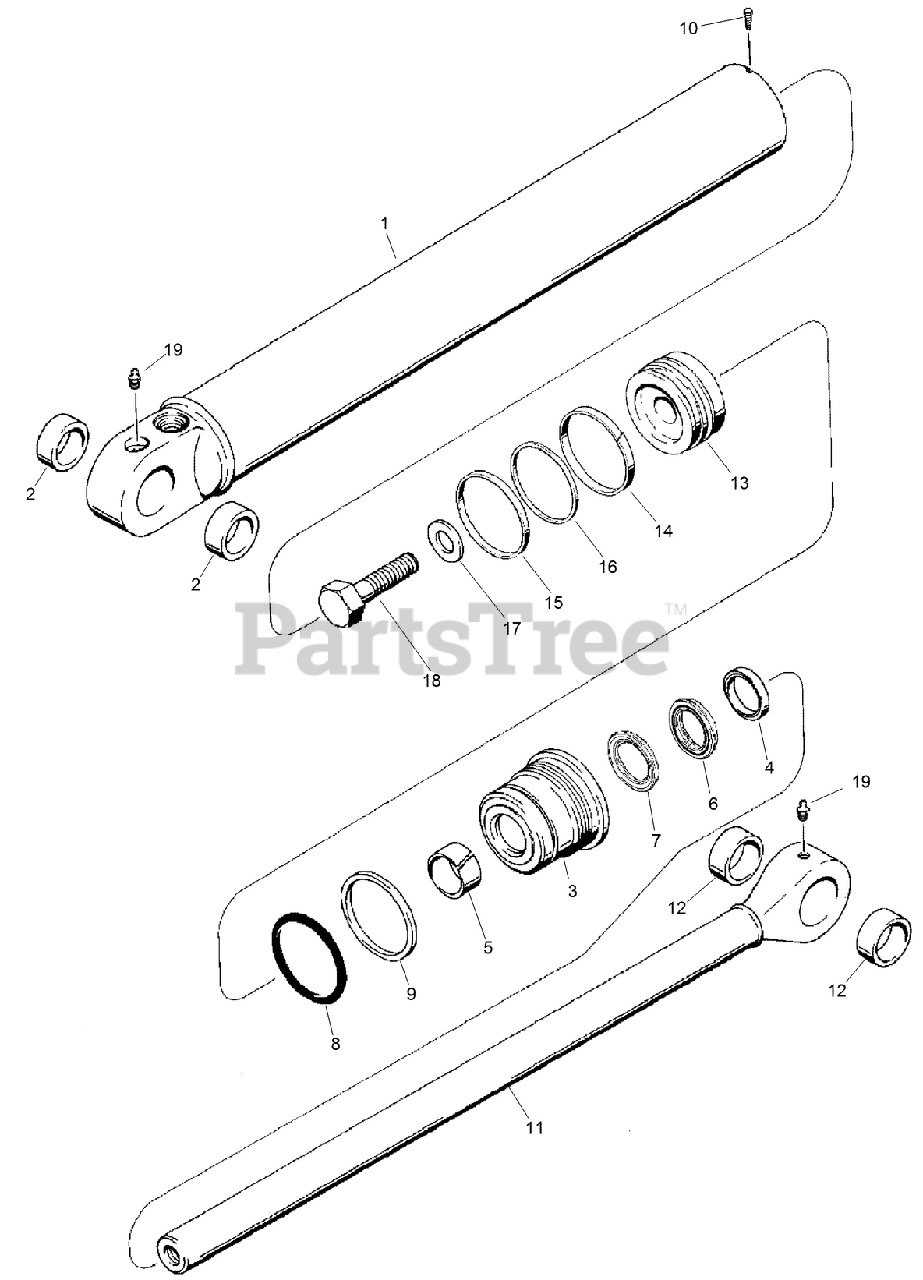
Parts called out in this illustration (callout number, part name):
1	TUBE-Cylinder
2	BUSHING
4	WIPER-ROD
5	BEARING-ROD
6	SEAL-Rod, NSS, order 1543256C1 kit, see below
7	SEAL-Buffer, NSS, order 1543256C1 kit, see below
8	O-RING
9	RING-BACKUP
11	ROD-Piston, 38 mm diameter
12	BUSHING
14	RING-WEAR
15	SEAL-Piston
16	RING-LOADER
17	WASHER
19	FITTING-Lube 1/8-27 Dryseal PTF
